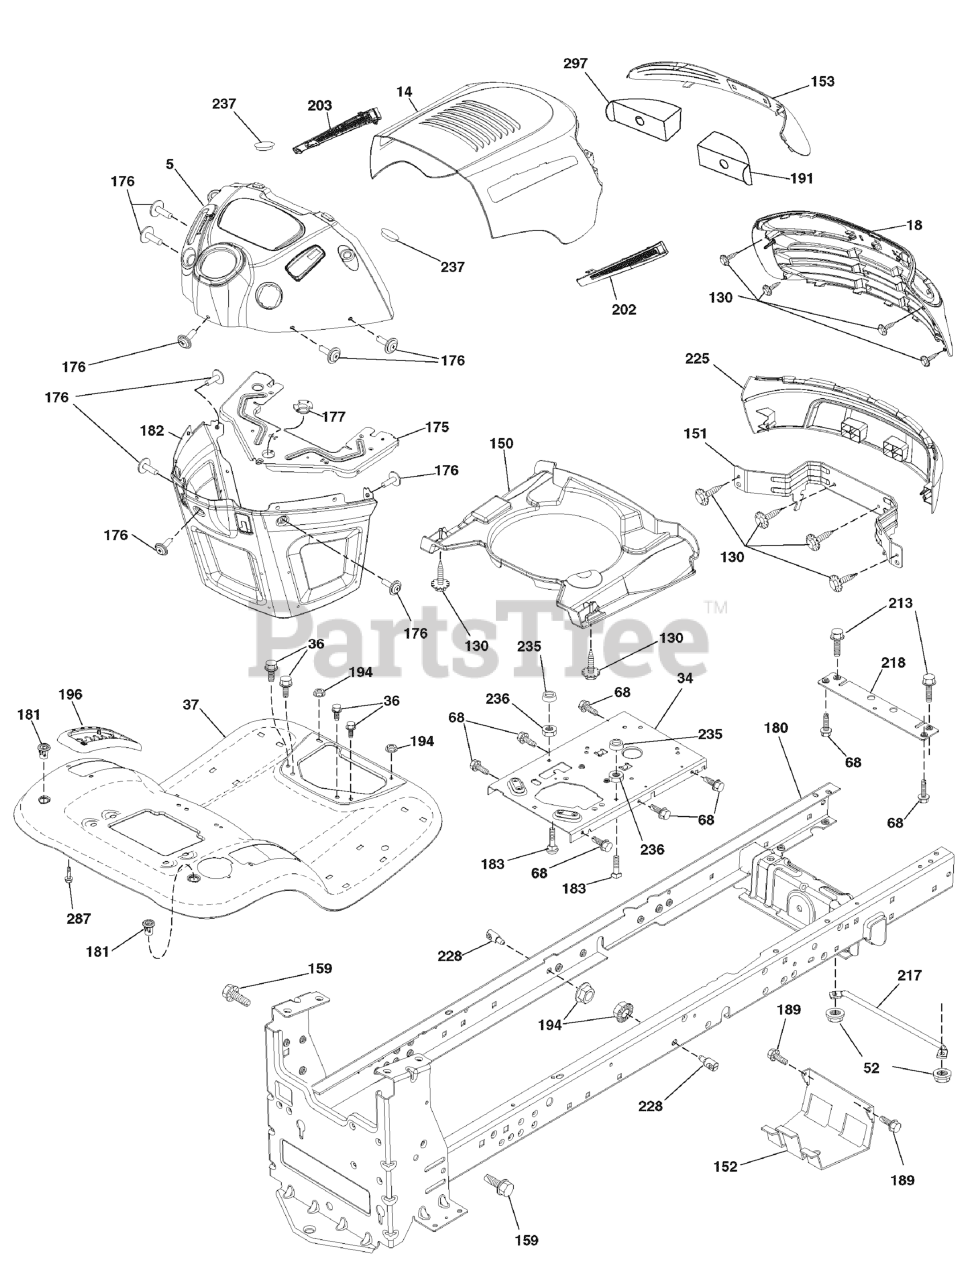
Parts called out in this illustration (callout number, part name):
18	** Grille
25	Lens Grille RH
34	Plate Engine
36	Screw 5/16-18 x 3/4
37	** Fender
52	Nut Crown Lock 5/16-18
68	Screw Thdrol 5/16-18 x 1/2
130	Screw #10 x 0.750
138	Cupholder
150	Duct Heat Hood
151	Bracket Pivot
152	Shield Browning
159	Screw Hexwsh Thdrol 3/8-16 x 3/4
175	Crossmember
176	Screw 10-24 x 5/8 Wshd Qdrx
177	Bushing Steering
180	Chassis
181	Bushing Mtg. Fender Crgo.
182	Dash Lower
183	Bolt 5/16-18 x 1-1/4
189	Screw 5/16-18 x 3/4
191	Insert Reflective RH
194	Nut Lock Hex Flange 5/16-18
196	Console Asm. Deck Lift
202	** Side Vent RH
203	** Side Vent LH
213	Bolt Hex HD 5/16-18 unc x 3/4
217	Rod Pivot Chassis
218	X-Piece Hood Stop
225	Bumper
228	Stud Fastener
235	Spacer Fender
236	Nut Center Lock 5/16-18
237	Plug Mount Cargo
287	Screw hex 1/4-20 x 3/8
297	Insert Reflective LH
